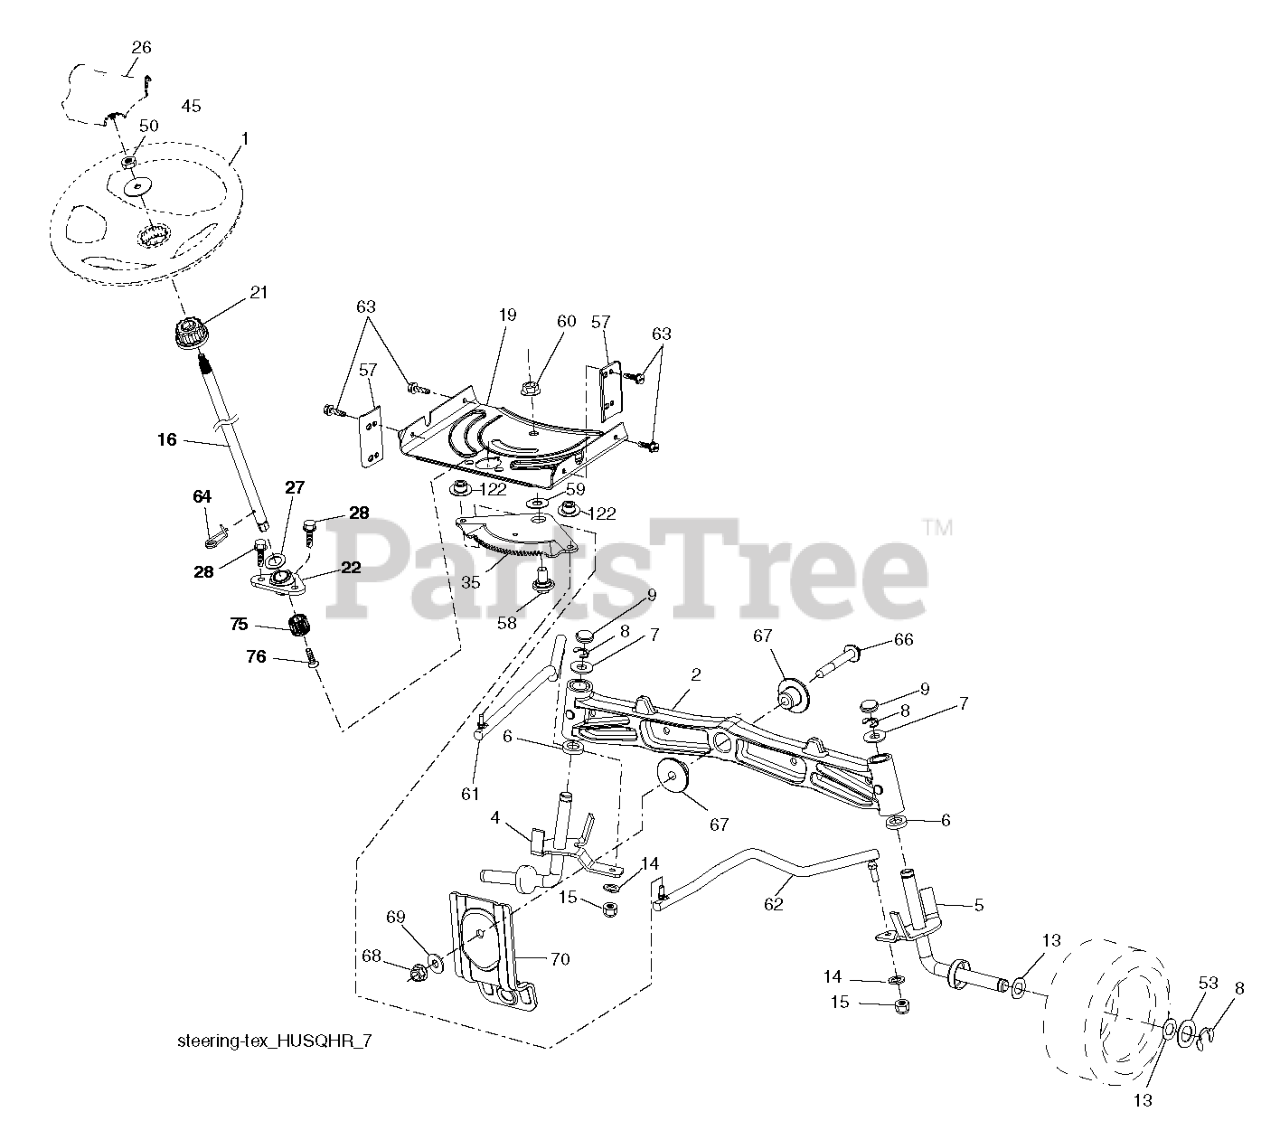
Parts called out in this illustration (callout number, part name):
1	WHEEL.STEER.HUSQ.SR.498.OVMLD
2	AXLE.CAST.IRON
4	SPINDLE.WELDED.LH.15"TEX
5	SPINDLE.WELDED.RH.15"T
6	THRUST WASHER
9	CAP.SPINDLE.BLACK
14	SLW 3/8 STD
15	NUT CROWNLOCK 3/8-24
16	SHAFT.STEER.2HIGH.SPLND.PLATED
19	PLATE.STEER.DDL.NLT/NG
21	ADAPTER.WHEEL.STEER.SPLND.ALUM
22	BEARING.SHAFT.STEER.LOWER.625
26	INSERT.CAP.WHL.STRG.HUSQ.PREM
28	SCREW, 3/8-16X3/4
35	GEAR.SECTOR.PLATE.DDL.
45	WASHER 9/16"ID, 2 3/8"OD
50	NUT LOCK FLG 3/8-16 UNC
53	WASHER.HARDENED
57	BRACKET.UPSTOP.TEX
58	BOLT.SHOULDER.SECTOR.P
59	WASHER.THURST.SECTOR.S
60	NUT FLANGE LOCK 5/8-11
61	DRAGLINK.LH.BALLSTUD.D
62	DRAGLINK.RH.BALLSTUD.D
63	SCREW
64	RETAINER.CLIP.SPRING.S
66	BOLT HEX FGHD 7/16-14 X 3 SERR
67	BUSHING.PM.FRONT AXLE
68	NUT.LOCK.FLANGE.7/16
69	WASHER.1.5X.505X.118
70	BRACKET.FRT.DECK.SUSP.RR.MT431
75	PINION.ZINC PLATED
76	SCREW HEAD SOCKET LRVB
122	CAP.GEAR.SECTOR.TEX
